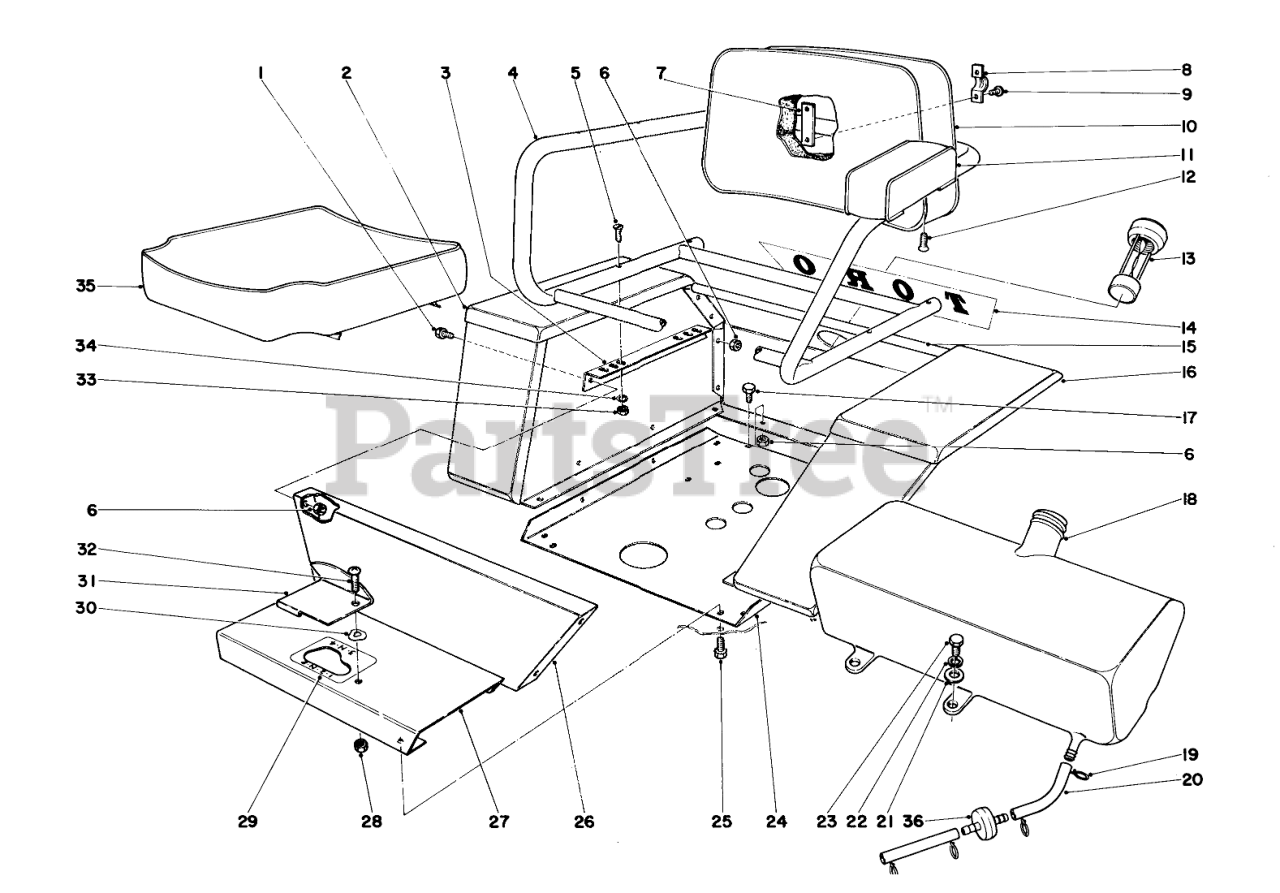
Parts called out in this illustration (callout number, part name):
1	SCREW-HH
2	Fender R.H.
3	Brace Fender
4	Frame Seat
5	Flat Head Screw
6	Nut
7	Plate Clamp
8	U-Clamp
10	Backrest Seat
11	Arm Rest Seat
12	Flat Head Screw
13	Gas Gauge
14	Decal Seat
15	Rear Fender
16	Fender L.H.
17	SCREW-HH
18	Gas Tank
19	Hose Clamp
20	Gas Hose
21	WASHER-FLAT
22	WASHER-LOCK
23	SCREW-HH
24	Base Fender Rear
25	Self Tapping Screw
26	Fender Front
27	Shift Pattern
29	Decal Shift Pattern
30	Lynch Pin
31	Tab Lock out
33	NUT-HEX
34	WASHER-LOCK
35	Cushion Seat
36	Filter Gas Tank
